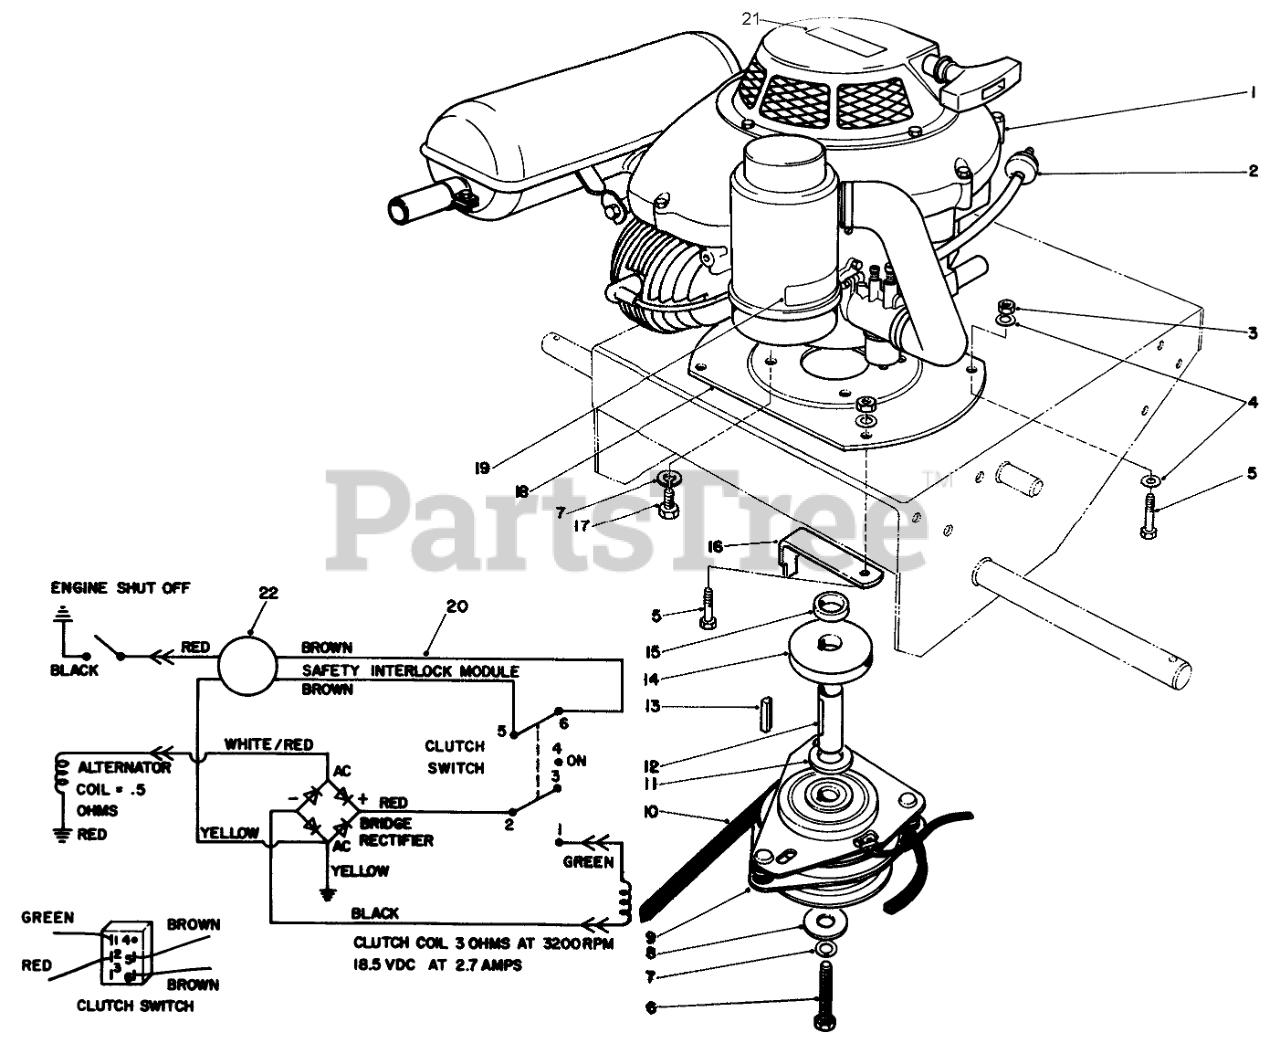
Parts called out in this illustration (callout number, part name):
1	Engine Assembly
2	FILTER-FUEL
3	NUT-LOCK, CONE
4	WASHER-PLAIN
5	SCREW-HH
6	CAPSCREW
7	WASHER-LOCK
8	WASHER-CLUTCH
9	CLUTCH/BRAKE
10	V-BELT, DRIVE
11	SPACER-LOWER
12	CRANK ADAPTER JLO
13	CRANKSHAFT KEY
14	Pulley-Drive
15	UPPER SPACER
16	Retainer-Clutch
17	CAPSCREW
18	ENGINE PLATE
19	DECAL
20	WIRE HARNESS JLO
21	DECAL
22	Module
